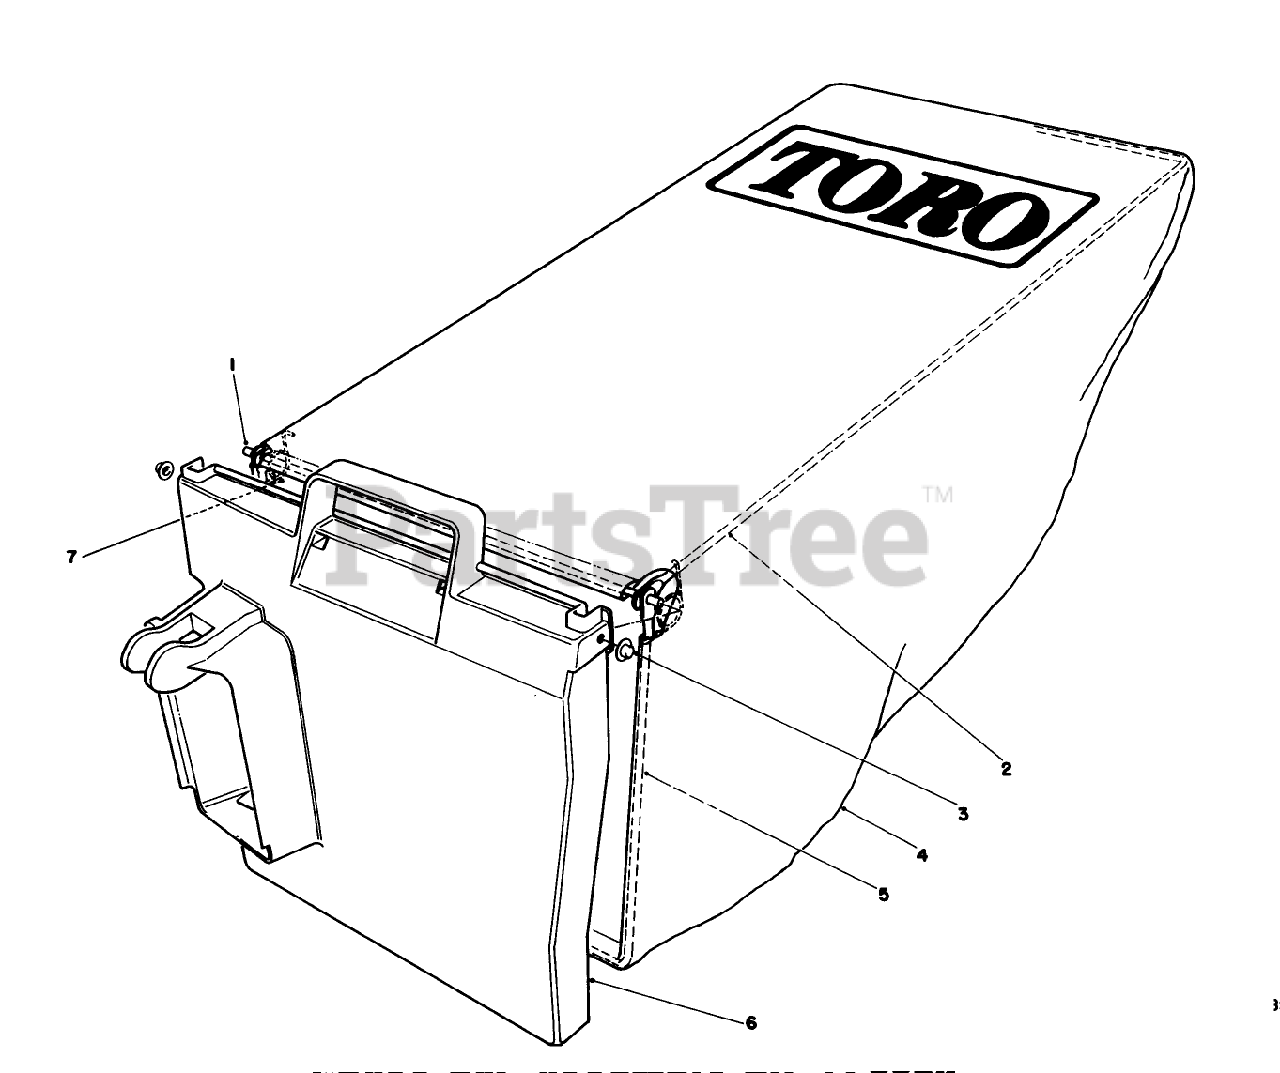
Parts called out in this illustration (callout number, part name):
1	HINGE PIN
2	BAG FRAME
3	NUT-PUSH
5	BAG FRAME
6	GRASS BAG DOOR
7	SPRING
